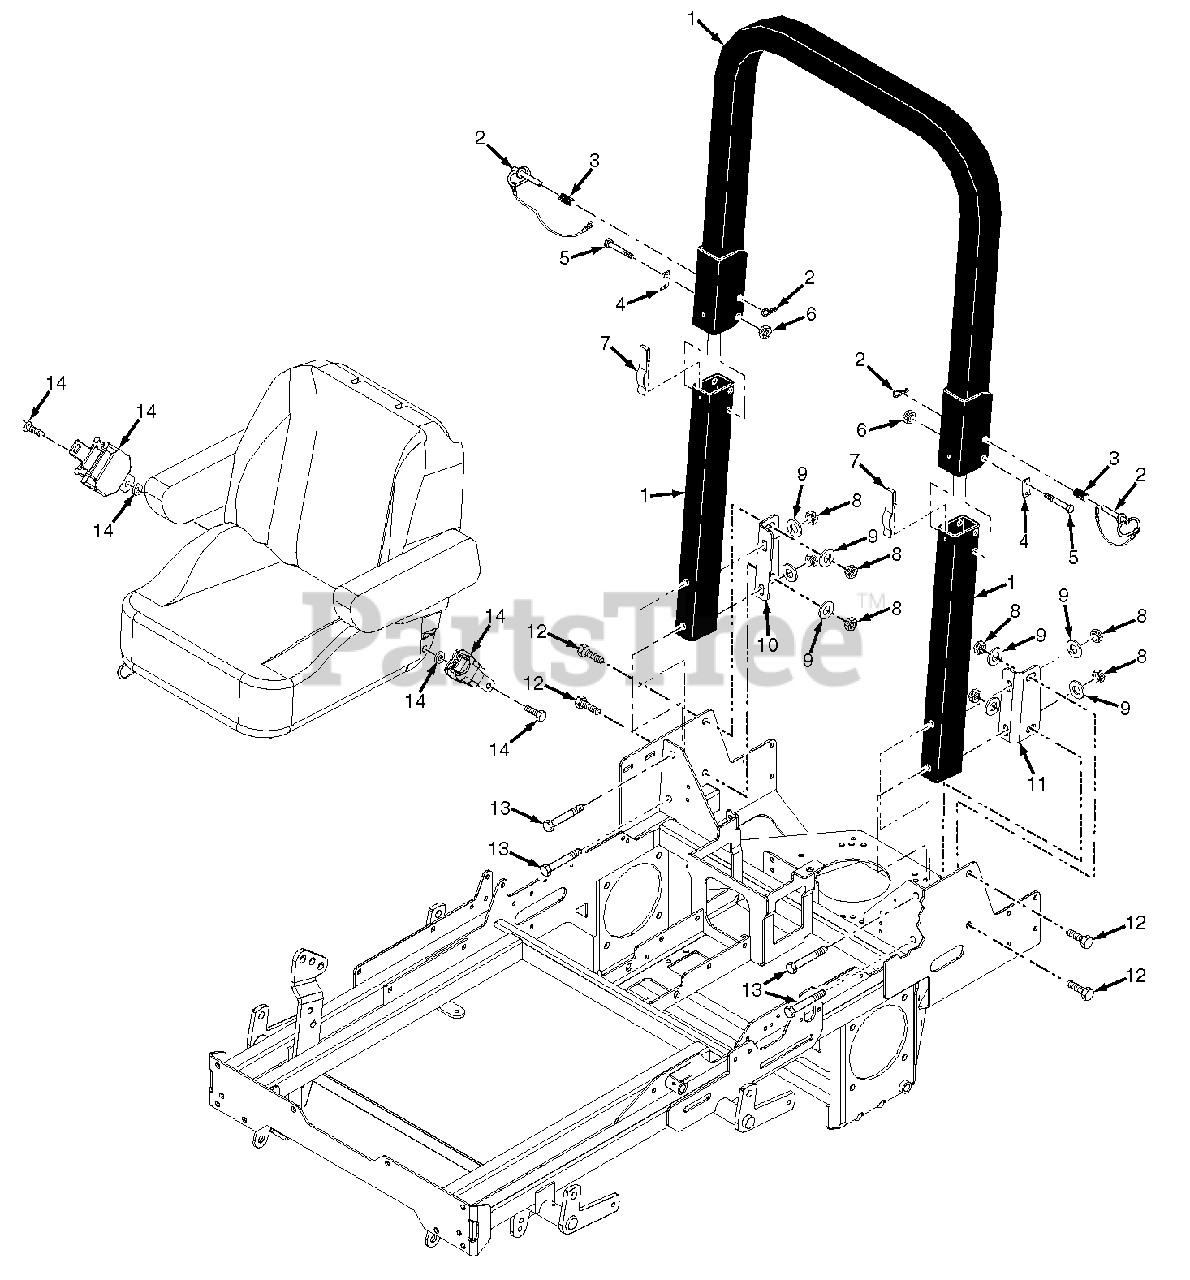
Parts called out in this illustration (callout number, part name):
1	ROPS, Foldable SCZ
2	Pin Assembly
3	Spring, ROPS
4	Clip, ROPS
5	Bolt, Hex Head 1/2-13 x 3-1/4"
6	Nut, Elastic Stop 1/2-13
7	Spring Clip, ROPS
8	Nut, Center Lock 1/2-13
9	Flatwasher, 1/2-.562 x 1.375 x .109
10	ROPS Mount, RH Rear
11	ROPS Mount, LH Rear
12	Bolt, Hex Head 1/2-13 x 1-1/4"
13	Bolt, Hex Head 1/2-13 x 4-1/4"
14	Seat Belt Kit, Retractable - SCZ
